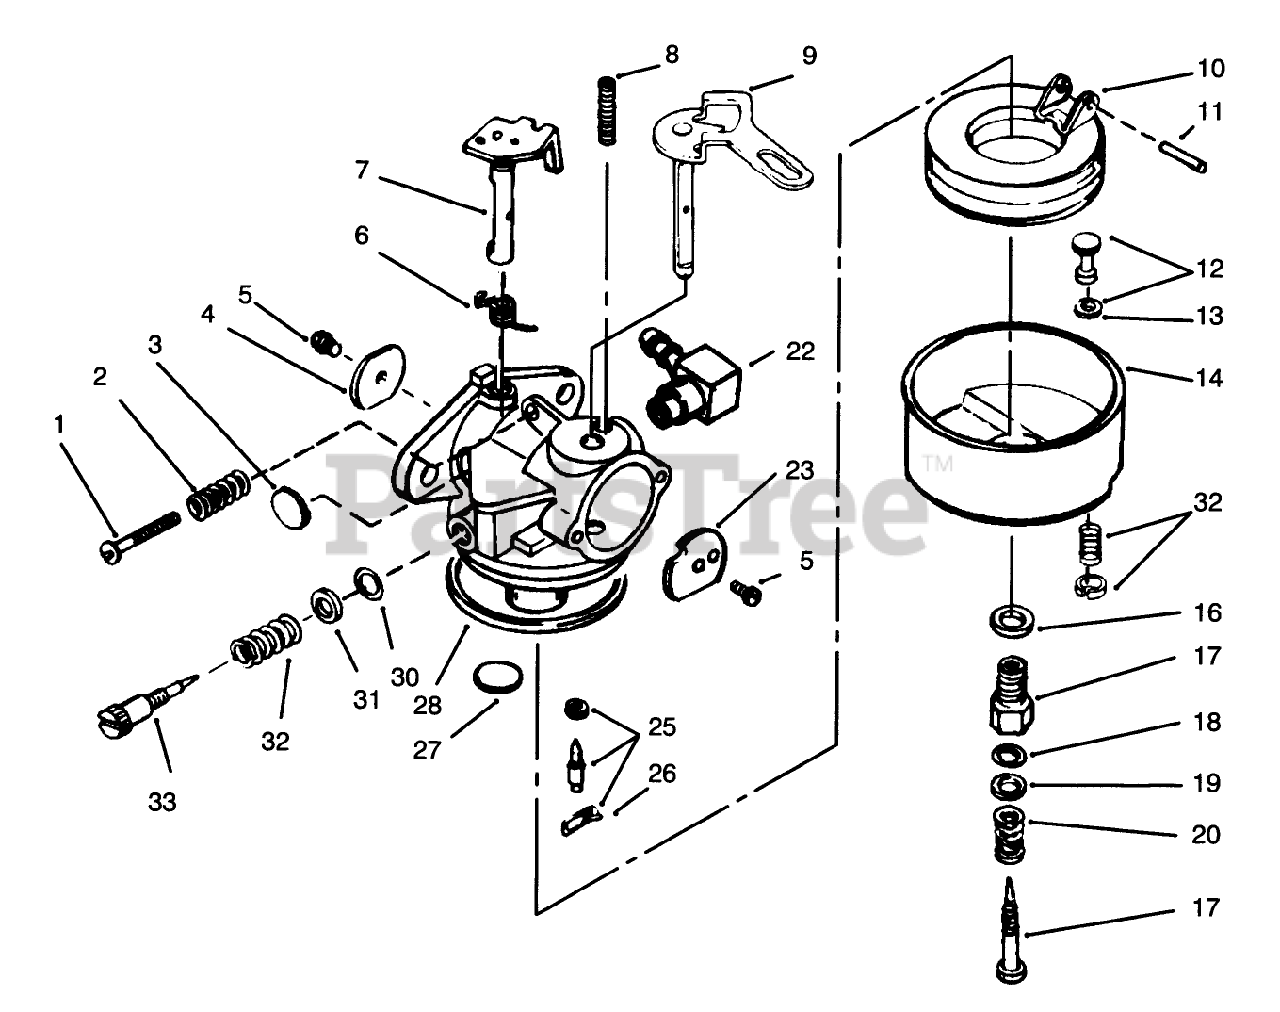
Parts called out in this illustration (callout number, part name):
1	Screw-Throttle Crack Screw / Idle Speed
2	Spring-Tension
3	Plug-Welch, Idle Mixture Well
4	Shutter-Throttle
5	Screw-Shutter
6	Spring-Return, Throttle
7	Throttle Shaft and Lever ASM
8	Spring-Positioning, Choke
9	Choke Shaft and Lever Asm
10	Float
11	Shaft-Float
12	Bowl Drain ASM
13	Gasket-Plunger, Drain
14	Float Bowl Asm. (Incl. Ref. # 32, 33)
16	Washer-Bowl Nut
17	Adjustment Screw Assy., Main (Incl. Nos. 5A, 21 23)
18	ORing
19	Washer
20	Spring
22	Fitting-Fuel
23	Shutter-choke
25	Inlet Needle, Seat Clip Assy. (Incl. No. 13)
26	Clip-Spring
27	Plug-Welch, Atmospheric Vent
29	O Ring-Bowl, Float
30	ORing
31	Washer
32	Spring-Tension
33	Screw-Idle
